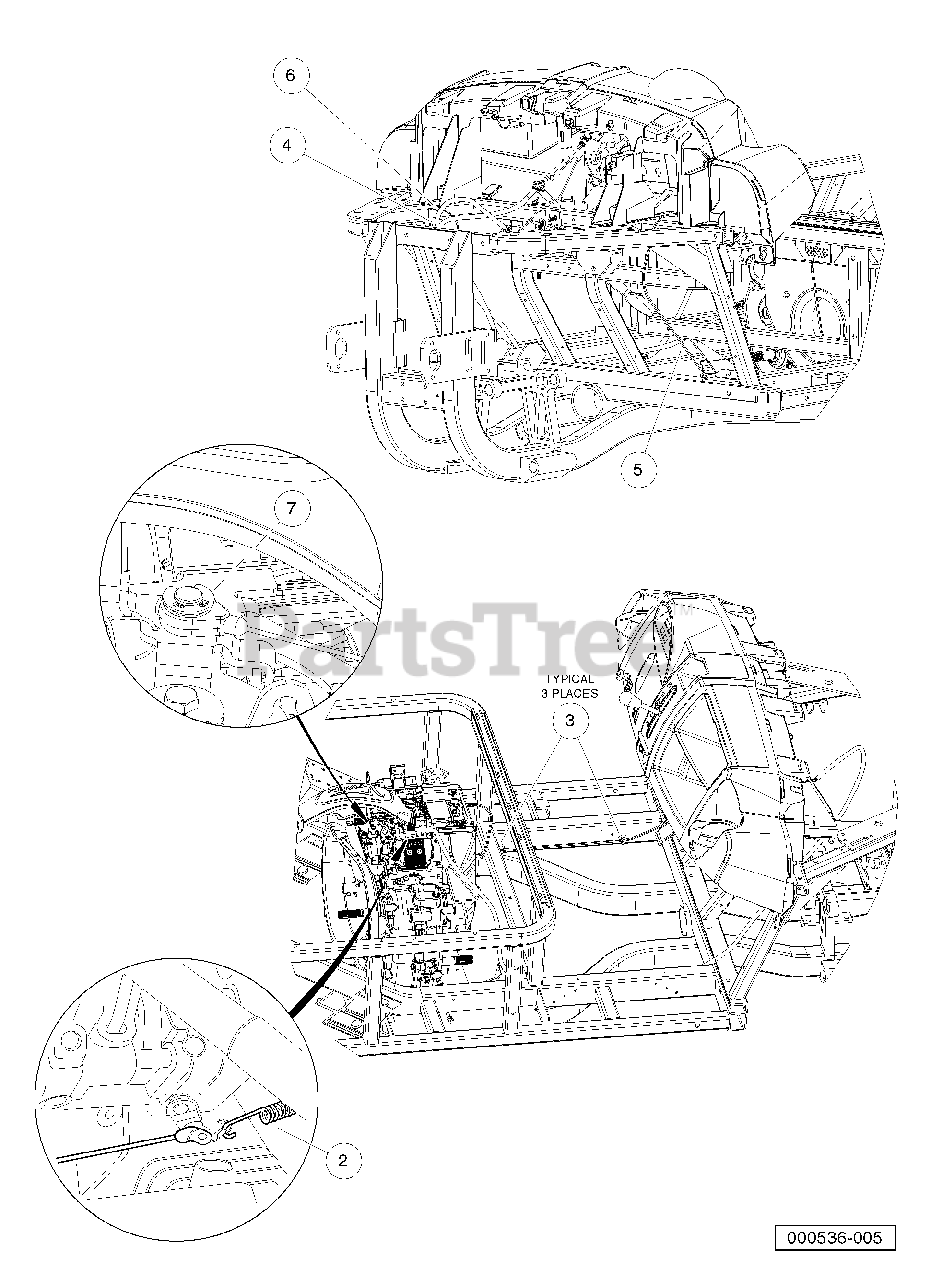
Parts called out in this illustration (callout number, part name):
1	Instl, Cable, Awd, Fh680d
3	Clip, Brake Line
4	Cable, Accel, AWD, Gas, FH680D
5	Cable, Choke, AWD, FH680D
6	Tie Wrap, 8" Nylon
7	Ring, Retaining
